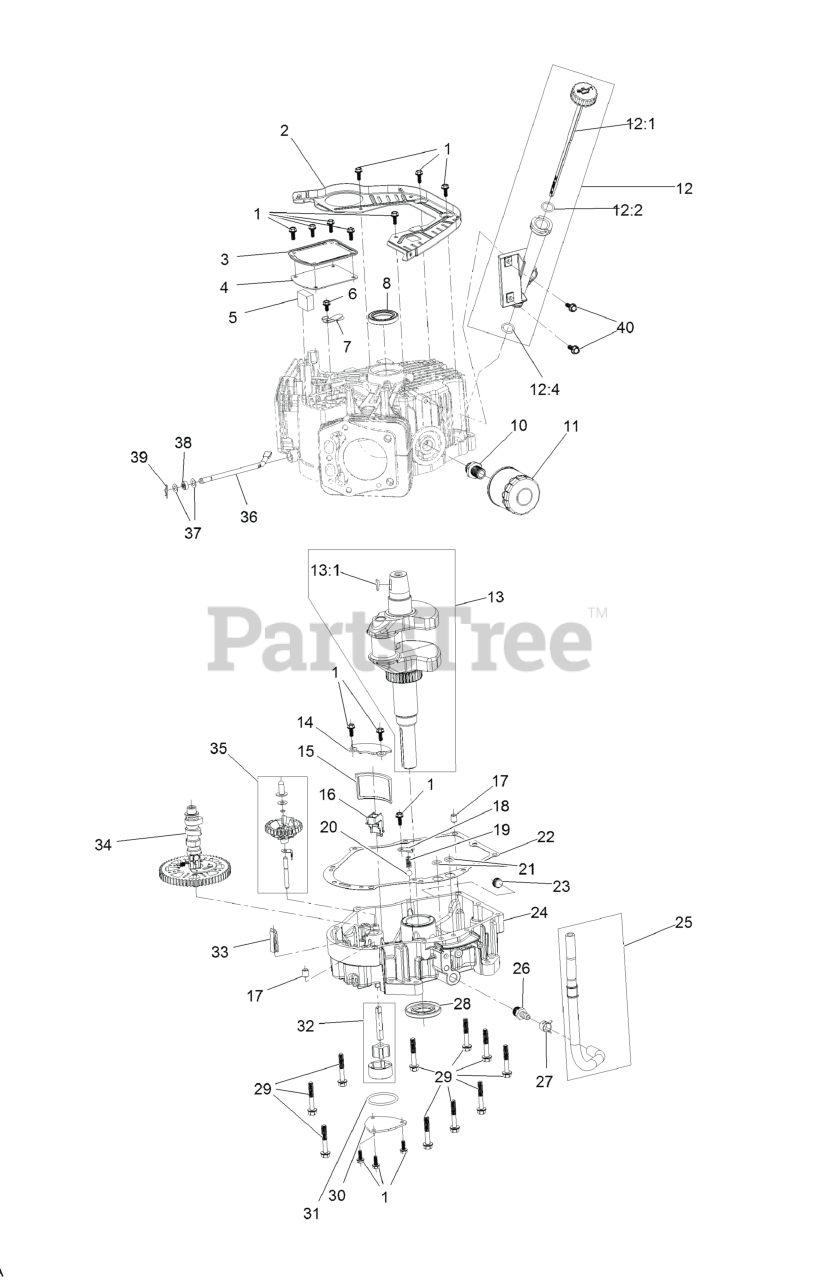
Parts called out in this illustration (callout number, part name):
1	SCREW-HHF
3	COVER-BREATHER
4	GASKET-BREATHER
5	FILTER-BREATHER
6	SCREW-HHF
7	VALVE-BREATHER
8	SEAL-OIL
10	ADAPTOR-FILTER, OIL
11	FILTER-OIL
12	OIL TUBE ASM
12:1	DIPSTICK
13	CRANKSHAFT
13:1	KEY-WOODRUFF
14	COVER-SCREEN, OIL
15	SCREEN-OIL
16	RETAINER-SCREEN
17	PIN-DOWEL
18	PLATE-RETAINER
20	VALVE-BALL
22	GASKET-COVER, CRANKCASE
23	PLUG-DRAIN
24	COVER-CRANKCASE
25	OIL DRAIN HOSE ASM
26	FITTING-HOSE
27	CLAMP-HOSE
29	SCREW-HHF
30	COVER-OIL PUMP
32	OIL PUMP ASM
33	DEFLECTOR-OIL, RUBBER
34	CAMSHAFT
35	GOVERNOR ASM
36	SHAFT-GOVERNOR
37	WASHER-PLAIN
38	SEAL-OIL
39	PIN-HAIR
40	SCREW-HHF
